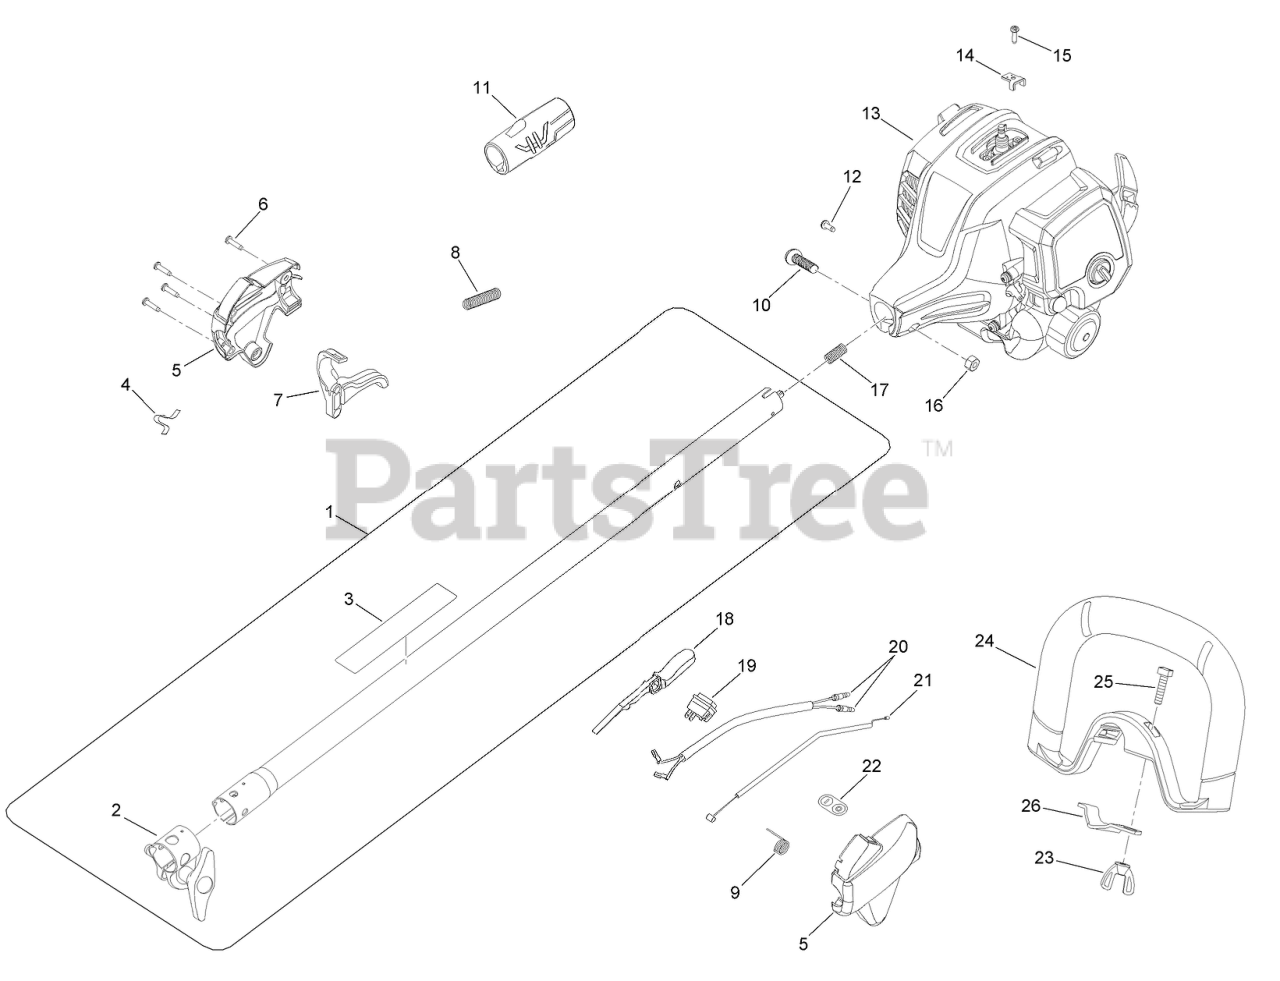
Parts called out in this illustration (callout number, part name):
1	UPPER SHAFT ASM
2	SHAFT CLAMP ASM
3	DECAL-WARNING
4	CLIP-STRAP, SHOULDER
5	CONTROL HANDLE ASM
7	TRIGGER
8	TUBE-CORRUGATED
9	SPRING-TRIGGER
11	GRIP-SHAFT, UPPER
13	Loose Parts Package
14	CLAMP-CABLE, THROTTLE
16	NUT-HEX
17	SPRING-COMPRESSION
18	LOCK-TRIGGER
19	SWITCH-ON/OFF
21	CABLE-THROTTLE
22	LABEL-ON/STOP
23	NUT-WING
24	HANDLE-SHAFT, UPPER
26	CLAMP-HANDLE, UPPER SHAFT
